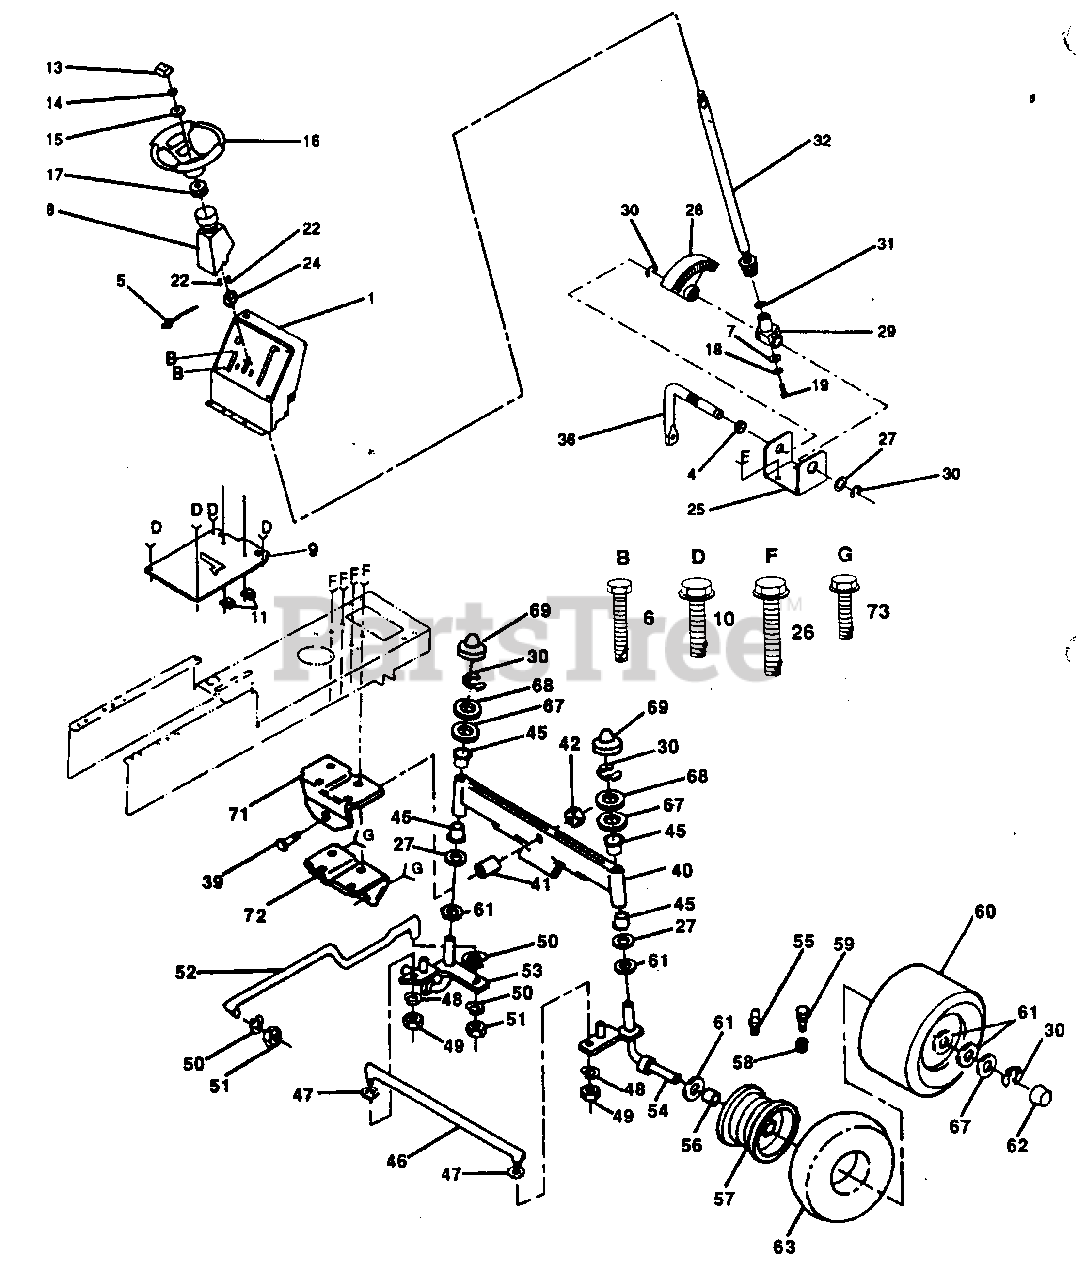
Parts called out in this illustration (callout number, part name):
4	Nyliner, Snap-in
5	Control, Throttle
6	Screw, Hex, Thread Cutting 1/4 - 20 x 5/8 TY23
7	Washer 5/8 x 1/4 x 16 Ga.
8	Tube, Steering Shaft
10	Screw, Hex, Washer Head Thread Rolling 3/8-16 x 1/2
11	Clip, Insulated
13	Insert, Steering Wheel
14	Locknut, Hex, Jam 1/2 - 20
16	Wheel, Steering
17	Adapter, Steering Wheel
18	Lockwasher 1/4
19	Screw, Socket Hex 1/4 x 20 x 5/8
22	Screw, Hex Tapping #10-16 x 1/2 Type ABTPS
24	Bushing, Steering
25	Bracket, Steering
26	Screw, Hex Washer Head, Thread Rolling 3/8-16 x 3/4 Type TT
27	Bearing, Thrust
28	Gear, Sector
29	Shaft, Support
32	Shaft, Steering
36	Shaft, Pitman
39	Bolt, Hex 5/8-11 x 3-3/4
41	Spacer, Bearing, Front Axle
42	Locknut, Flange 5/8-16
45	Bearing
46	Rod, Tie
47	Washer 11/32 x 3/4 x 16 Ga.
49	Nut, Hex 5/16-18
50	Washer, Lock 3/8
51	Nut, Hex 3/8 - 24
52	Link, Drag
53	Spindle, L. H.
54	Spindle, R. H.
55	Fitting, Grease
56	Bearing, Flange
57	Rim, Front (Inc. 2 Each Key No. 56)
61	Washer 25/32 x 1-1/4 x 16 Ga.
67	Washer 25/32 x 1-5/8 x 16 Ga.
68	Washer 27/32 x 1-1/4 x 16 Ga.
71	Support, Saddle, Rear
72	Support, Saddle, Front
73	Screw, Hex Washer Thdrol. 5/16-18 x 1/2
